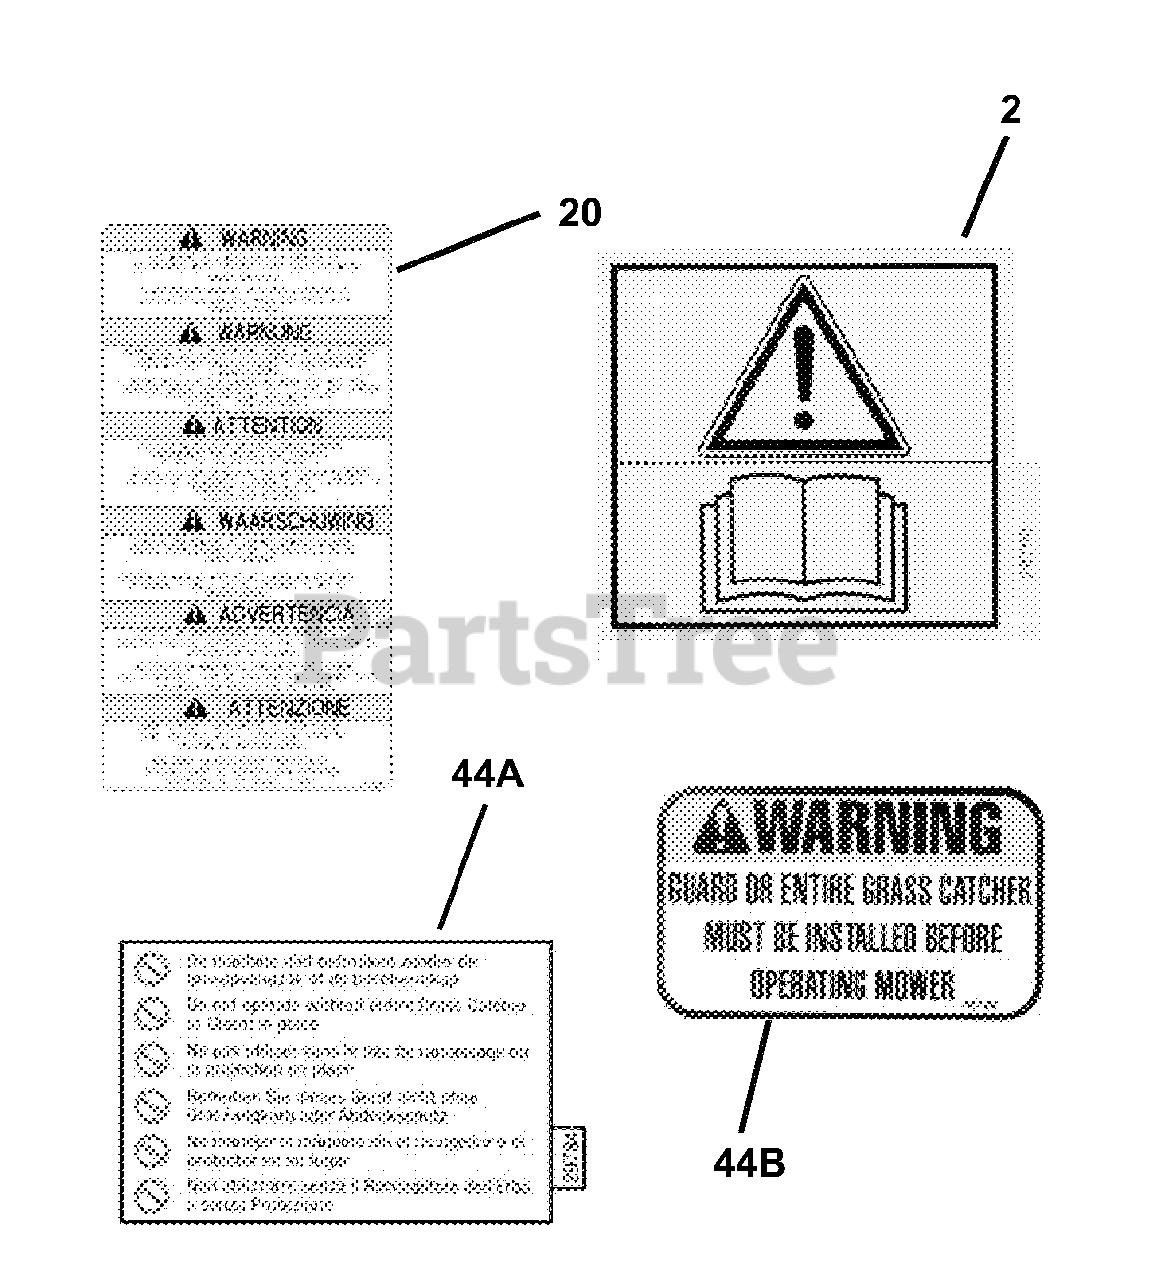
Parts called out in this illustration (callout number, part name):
2	DECAL, Read Manual
20	DECAL, Warning
44A	DECAL, International Warning
44B	DECAL, Chute/Deflector
